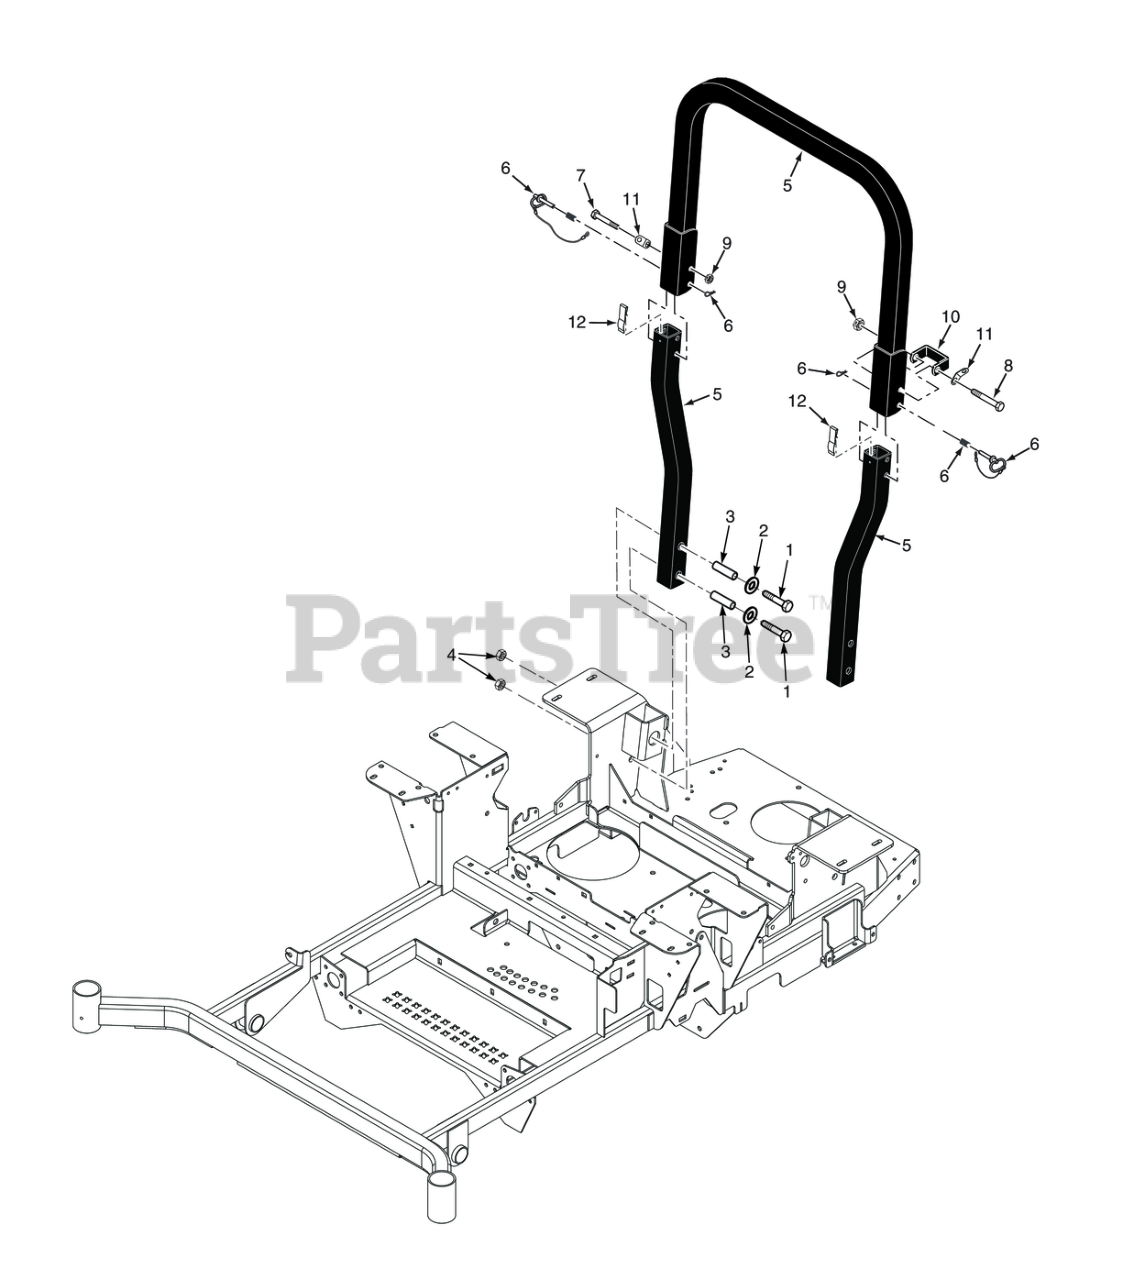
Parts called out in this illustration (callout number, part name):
1	Bolt, Hex Head 1/213 x 3" Gr. 8
2	Flatwasher, 1/2 - .531 x 1.062 x .095
3	Bushing, SFZ ROPS
4	Nut, Elastic Stop 1/2-13, (STT-52 & STTII-52)
5	ROPS, (Scag Gold)
6	Pin Assembly, ROPS Hinge
7	Bolt, Hex Head, 1/2-13 x 3-1/4"
8	Bolt, Hex Head 1/2-13 x 3-1/2"
9	Locknut, Hex 1/2-13 Center Lock
10	Stop, ROPS
11	Clip, ROPS
12	Spring, ROPS Anti-Rattle
